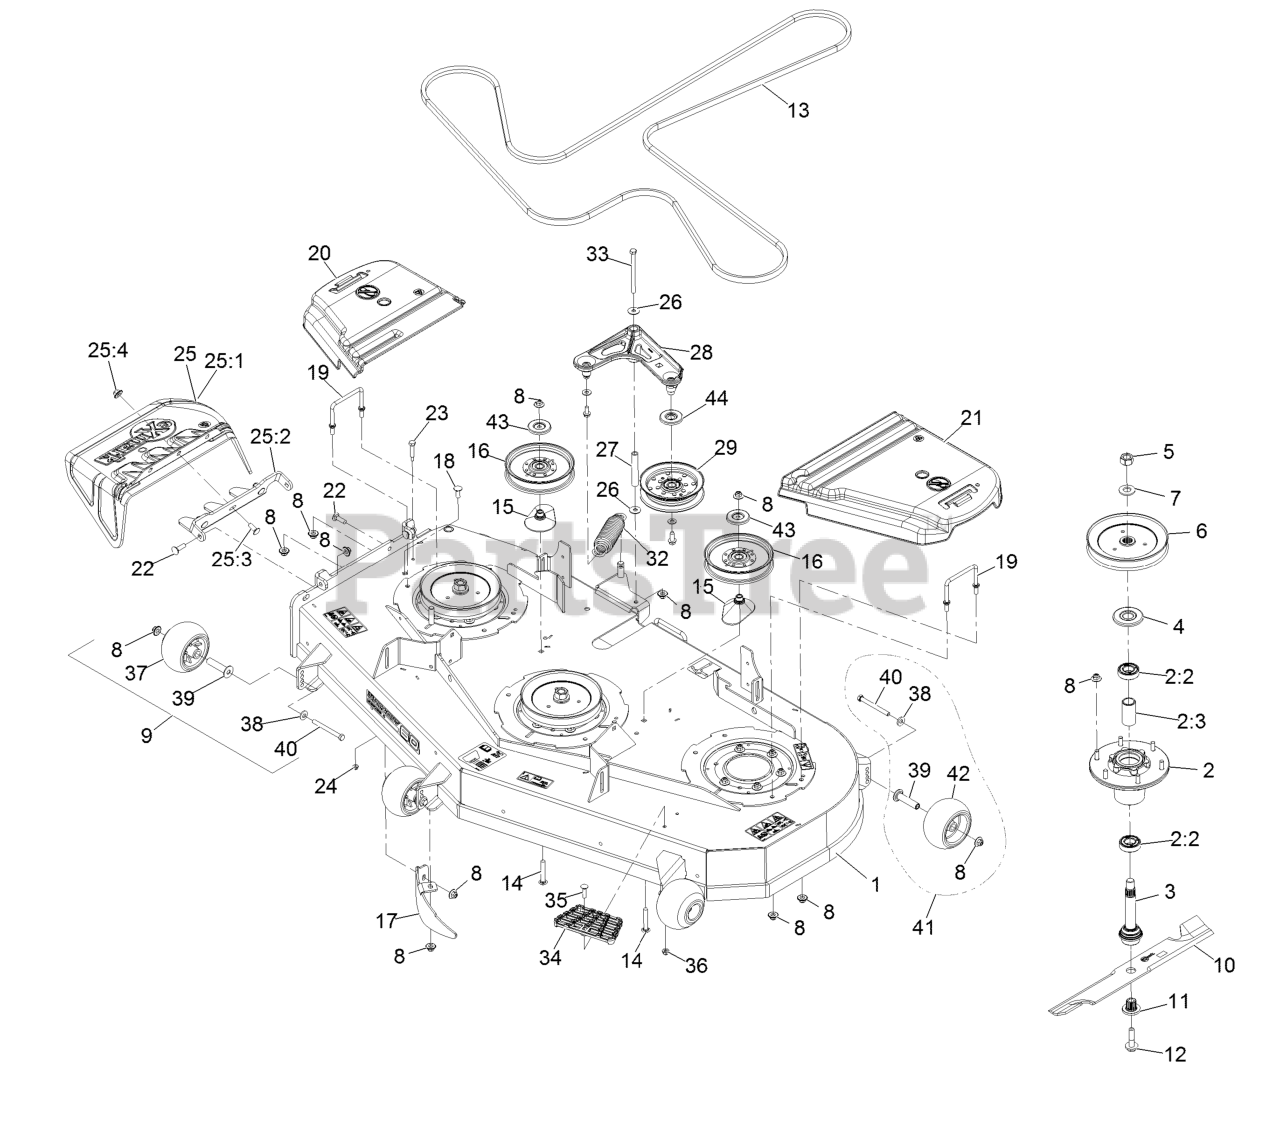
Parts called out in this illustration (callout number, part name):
1	ASM-Deck W/Decals 604
2	ASM-Cutter Hsg With Bearings
2:2	Bearing-Ball
2:3	Spacer-Bearing
3	ASM-Spindle And Seal
4	Guard,Bearing Top .989
5	Nut-Hex
6	Sheave,Blade Drive 7.25
7	Washer-Spring Disc 3/4
8	Nut-Nyloc 3/8-16 Flg
9	Kit, Anti-Scalp Roller
10	Blade-Extreme 2, 20.50"
10	Blade, Notched
10	Blade, Mulching
10	Blade, Low Lift
10	Blade, Solid
11	Bushing, Splined
12	Screw-Sems 1/2-20 X 2.19
13	Belt-V
14	Bolt-Carriage 3/8-16 X 2 1/2
15	Spacer-Pulley
16	Idler-Pulley, Flat 6.00X1.00
17	Dogleg - Lz60
18	Bolt-Carriage 3/8-16 X 1
19	Wireform-Cover
20	Cover-Belt, RH
21	Cover-Belt, LH
22	Bolt-Carriage 3/8-16 X 1 1/4
23	Bolt-Shoulder
24	Nut-Nyloc 1/4-20 Flg
25	ASM,Discharge Chute
25:1	Chute, Discharge
25:2	Bracket,Discharge Chute
25:3	Bolt-Carriage 3/8-16 X 1
25:4	Nut-Nyloc 3/8-16 Flg
27	Bushing
28	Idler Arm ASM
29	Idler-Pulley, Flat
32	Spring-Extension
33	Screw-HH 3/8-16 X 4 3/4
34	Step-Deck
35	Bolt-Carriage 5/16-18 X 1 1/4
36	Nut-Nyloc 5/16-18 Flg
37	Roller-Anti-Scalp
38	Washer-Spring Disc 3/8
39	Axle, Roller
40	Screw-HH 3/8-16 X 3 3/4 GR 8
41	Kit-Antiscalp Roller
42	Roller-Scalp, Anti
43	Shield-Dust
44	Shield-Guard, Dust
